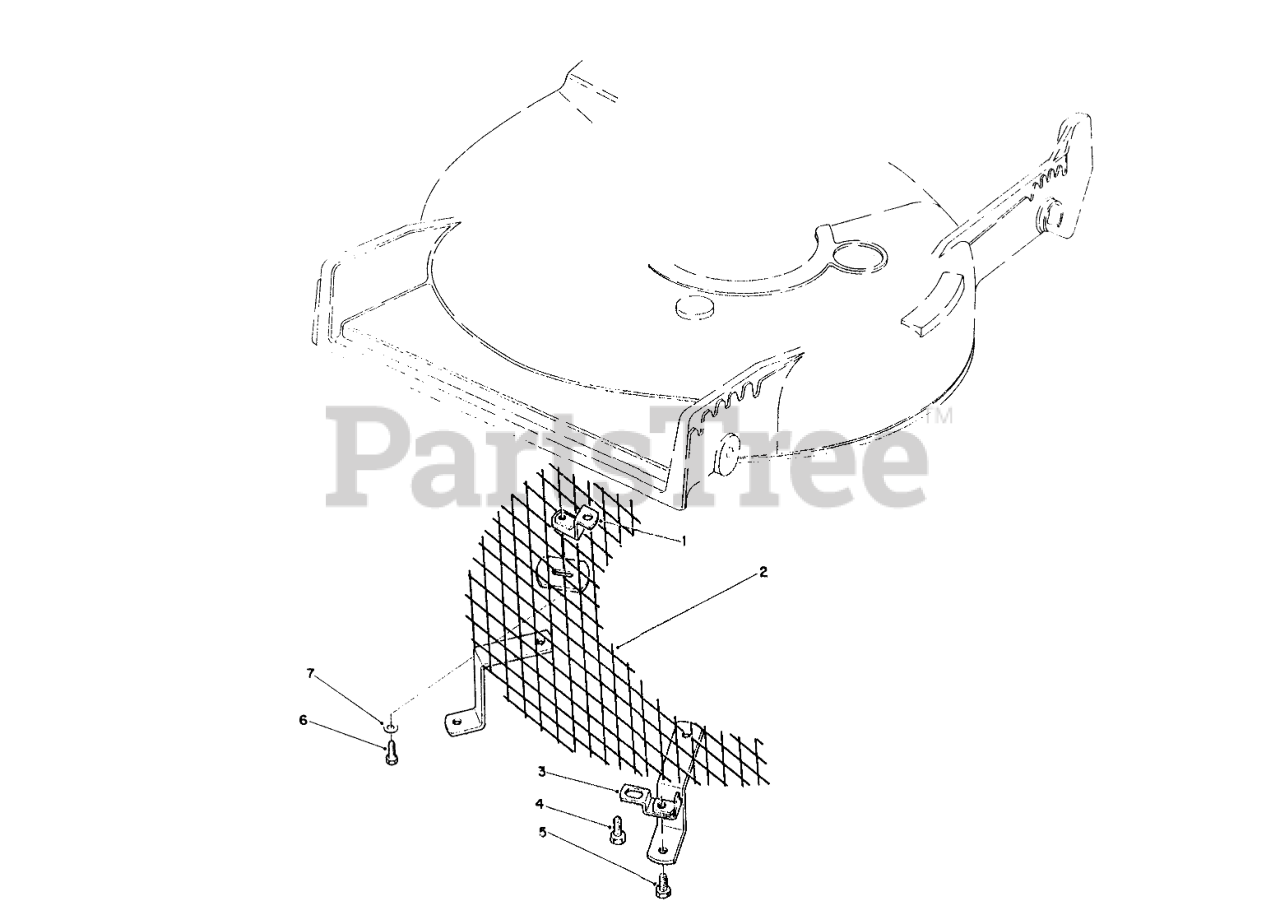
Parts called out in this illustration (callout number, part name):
1	BRACKET WA
2	SCREEN WA
3	MTG. BRACKET W.A.
4	SCREW-HWHTF
5	SCREW-HH
6	SCREW-HH
7	WASHER-FLAT
